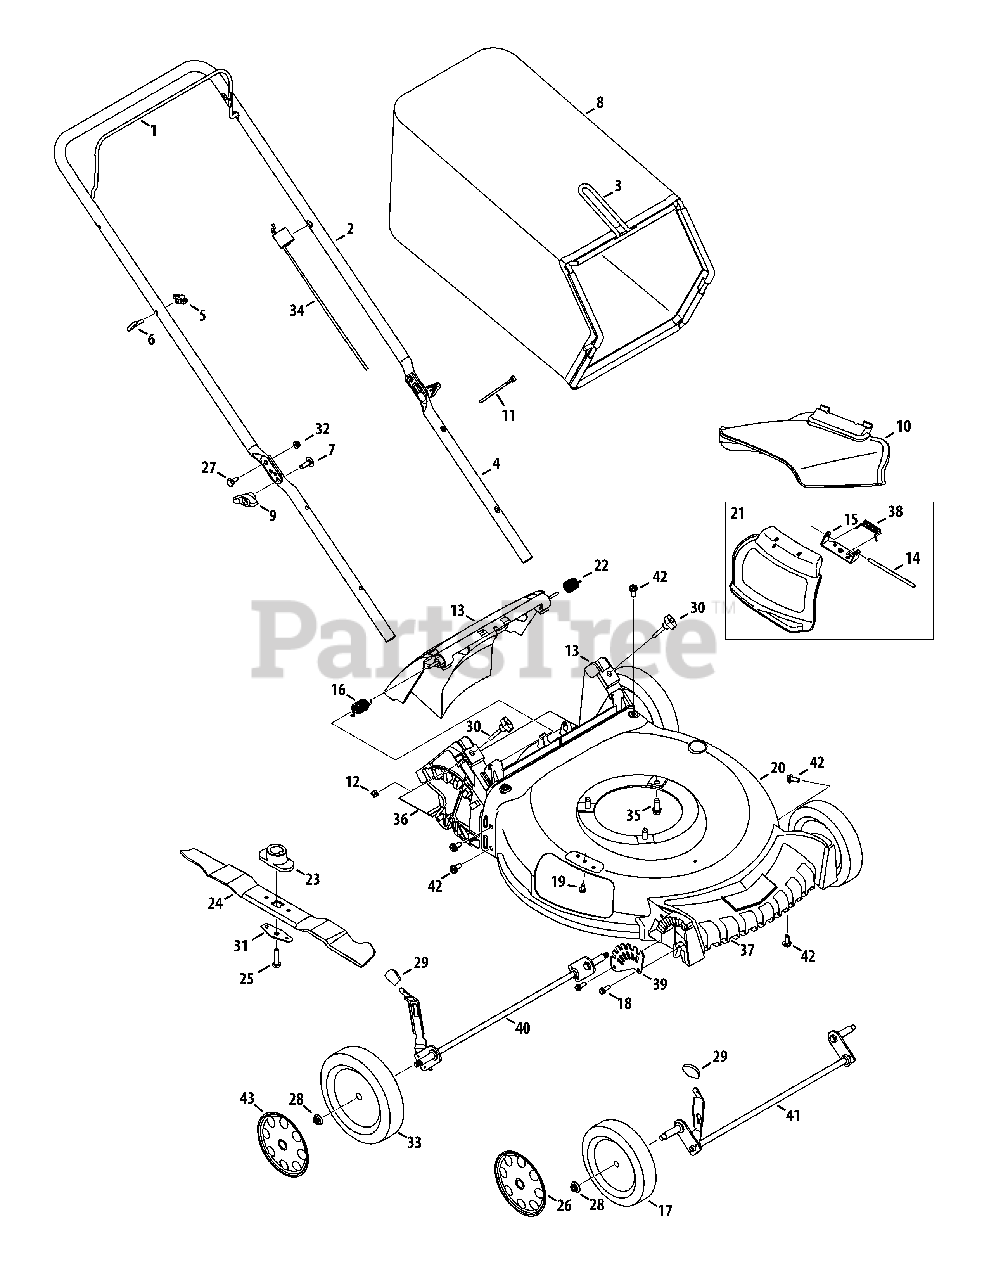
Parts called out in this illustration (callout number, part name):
1	Blade Control
2	Upper Handle
3	Grass Catcher Frame
4	Lower Handle
6	Rope Guide
7	Carriage Screw ,5/16-18
8	Grass Bag
10	Side Chute
11	Cable Tie
12	Nut, Sq., 1/4-20
13	Rear Discharge Door Assembly
15	Chute Deflector Bracket
16	Torsion Spring - RH
17	Front Wheel
18	Screw, 1/4-15 x .750
19	Screw, 1/4-20 x .500
21	Hinged Mulch Plug Assembly
22	Torsion Spring - LH
23	Blade Adapter, #6 x 1.19
24	Mulching Blade
25	Screw , 3/8-24 x 1.50
26	Hub Cap, 7"
27	Sldr. Screw, .375 x .126 x 1/4-20
28	Flange Lock Nut, 3/8-16
29	Adjustment Lever Knob
31	Blade Bell Support
32	Nut, Flange Lock, 1/4-20
33	Rear Wheel, 11"
34	Control Cable, Briggs
35	TT Sems Screw, 3/8-16 x 1.0
36	Trail Shield
37	Front Cover
38	Torsion Spring
39	Front Height Adjuster Plate
40	Rear Axle Assembly, 11"
41	Front Axle Assembly
42	Screw, 5/16-14 x .750
43	Hub Cap, 11"
